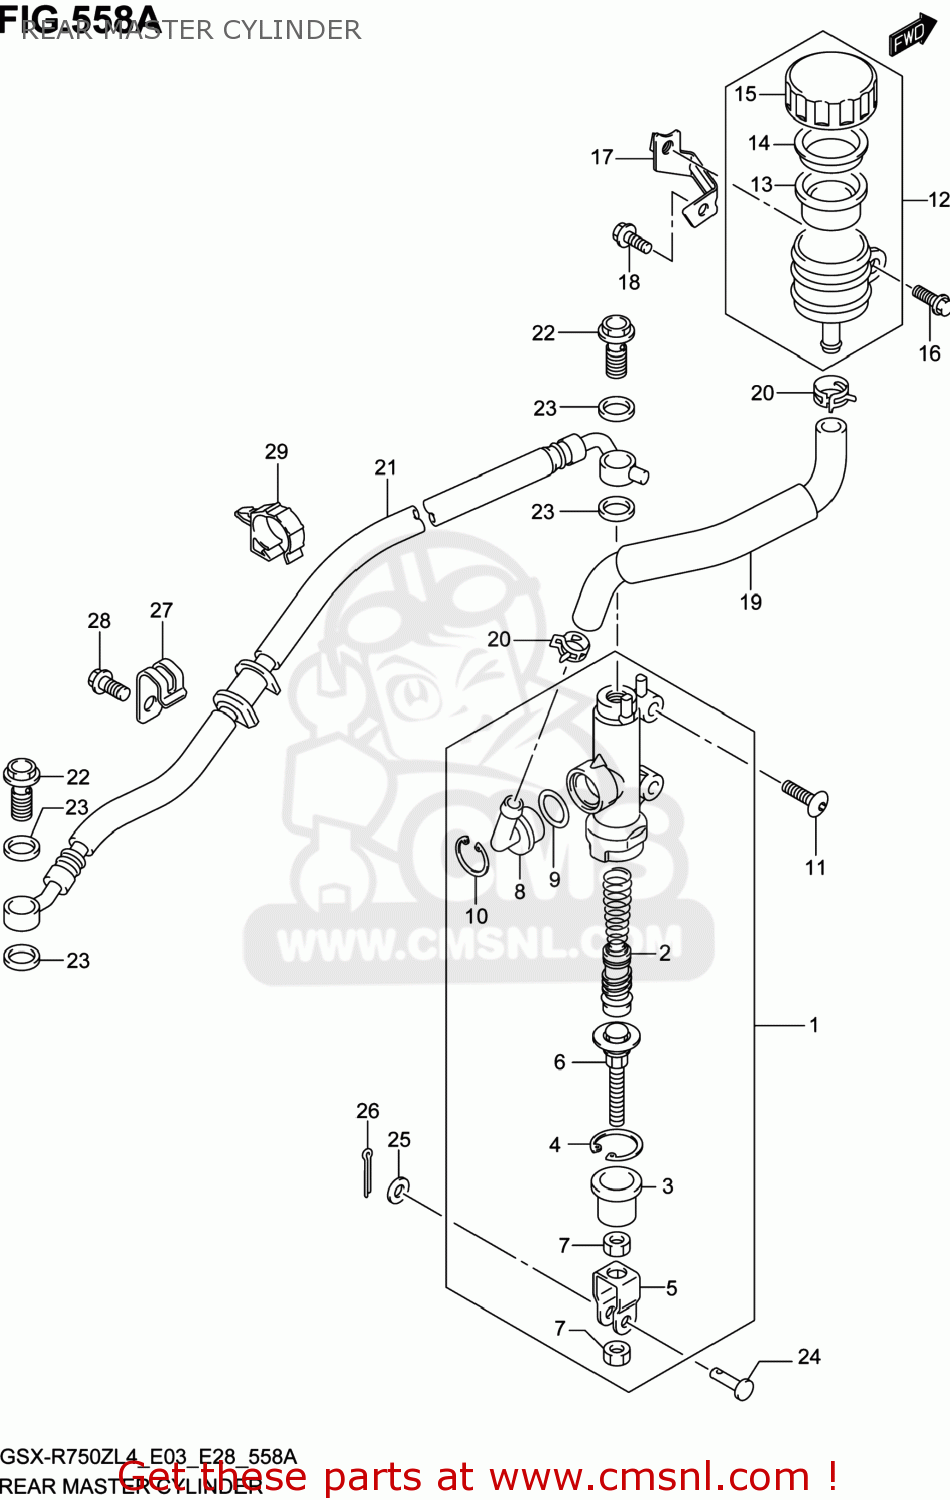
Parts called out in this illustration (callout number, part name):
1	CYLINDER ASSY,RR MASTER
2	PISTON/CUP SET
3	BOOT
4	CIRCLIP
5	YOKE
6	ROD,PUSH
7	NUT
8	CONNECTOR
9	O RING
10	CIRCLIP
11	SCREW(6X20)
12	TANK ASSY,RR RESERVOIR
13	DIAPHRAGM
14	PLATE
15	CAP
16	BOLT
17	BRACKET,RR RESERVOIR TANK
18	BOLT
19	HOSE,RR RESERVOIR TANK
20	CLIP
21	HOSE,RR BRAKE
22	BOLT UNION
23	WASHER(10X15X1.5)
24	PIN(6X18.2)
25	WASHER
26	PIN
27	CLAMP,RR BRAKE HOSE
28	BOLT
29	CLAMP
